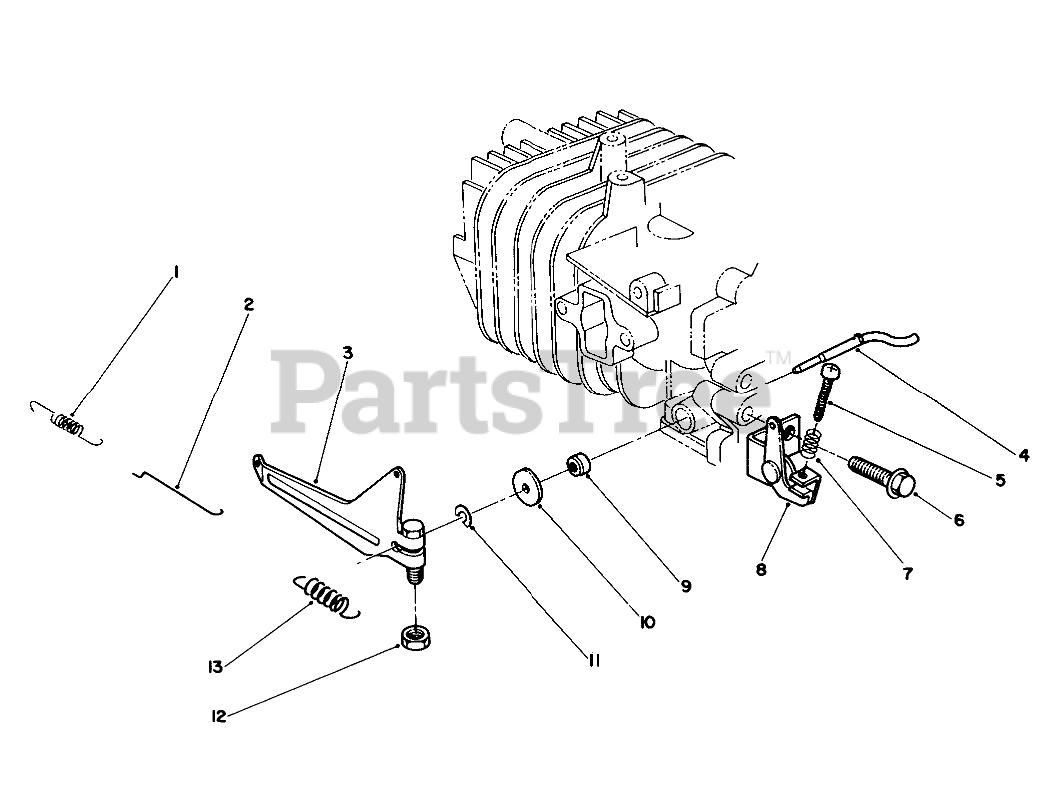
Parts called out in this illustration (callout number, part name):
1	CARB SPRING
2	CARB ROD
3	GOV ARM
4	SHAFT
5	SCREW
7	SPRING
8	GOV SPR BRKT
9	SEAL-OIL
10	WASHER
11	E-RING
13	GOV SPRING
